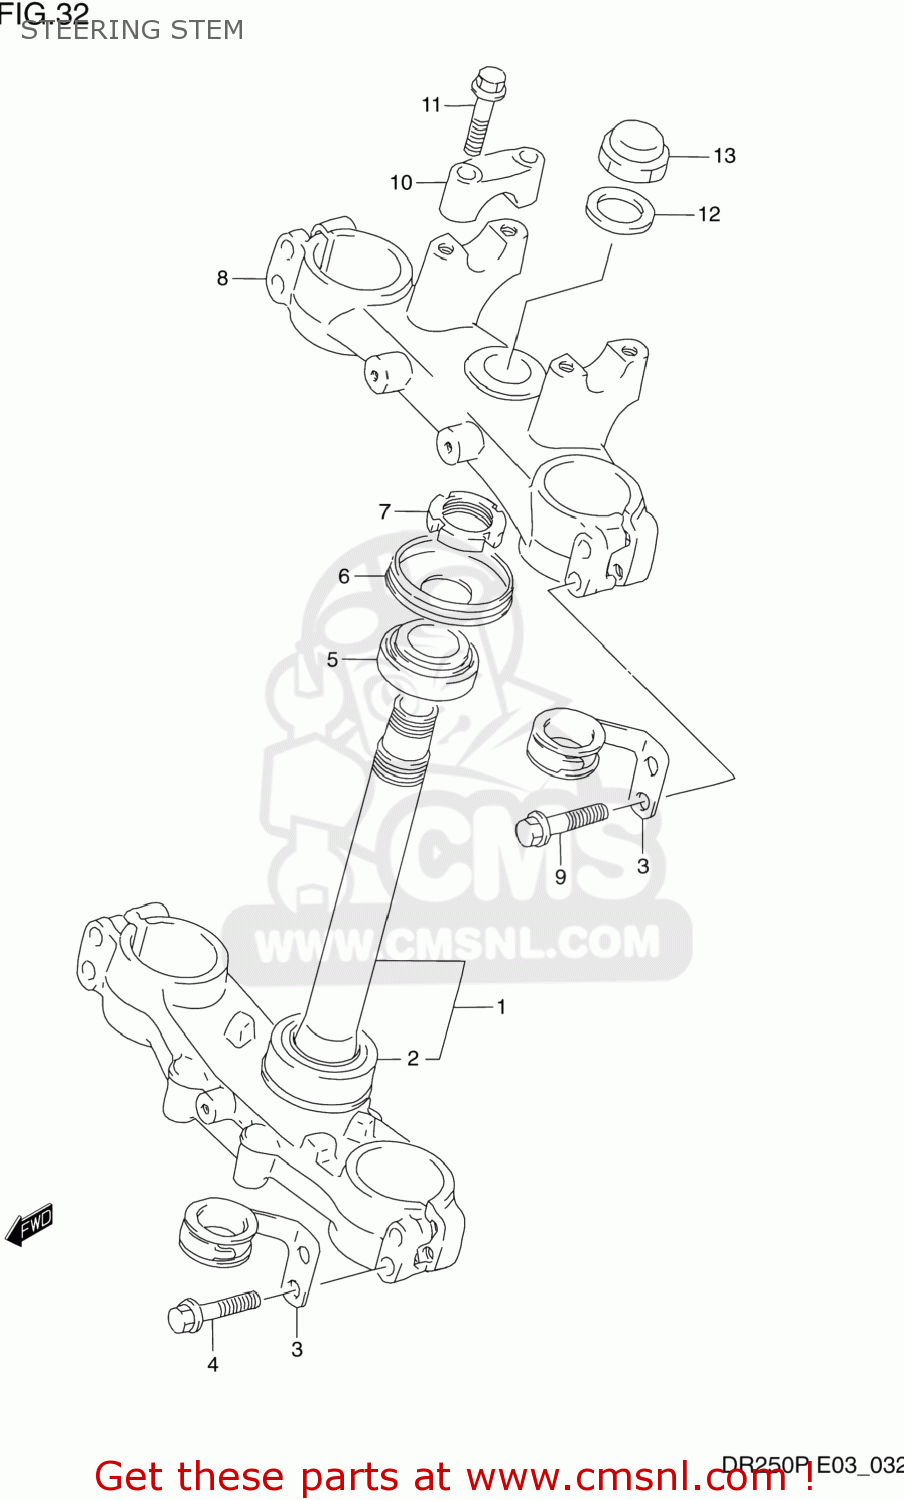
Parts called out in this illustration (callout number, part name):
1	STEM,STEERING
2	BEARING(30X55X17)
3	GUIDE,CABLE LWR,L
4	BOLT 8X40
5	TAPER,ROLLER BEARING
6	SEAL,STEERING UPR DUST
7	NUT,STEERING STEM
8	HEAD,STEERING STEM
9	BOLT 8X40
10	HOLDER,HANDLE UPR
11	BOLT
12	WASHER
13	NUT
